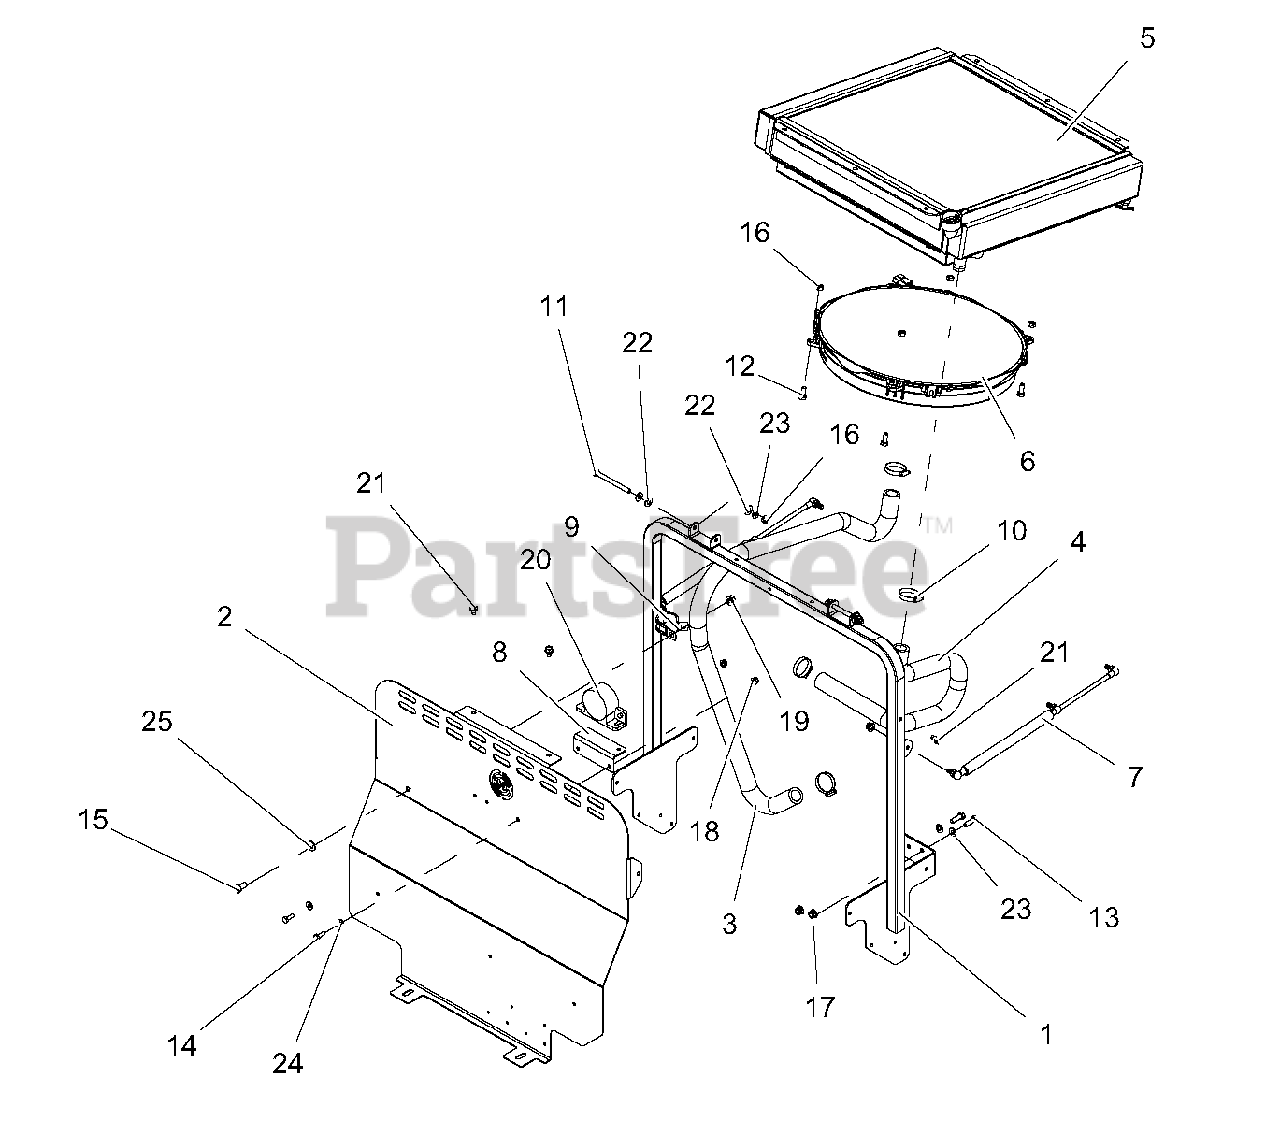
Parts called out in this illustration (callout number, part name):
1	WLDMT, RADIATOR / EXP. TANK MOUNTK-BLAC
2	GUARD, OPERATOR PT400 DIESEL
3	HOSE, FORMED RADIATOR OUTLET
4	HOSE, FORMED RADIATOR INLET
5	RADIATOR, DIESEL PT-400
6	FAN, COOLING 16"
7	Gas Shock
8	BRKT, SIGNAL MOUNT
9	CLAMP, CUSHIONED STEEL5, 1.2
10	CLAMP, HOSE 1.50 X .81 X 1.42
11	BLT-HEX .31-18X3.50 GR5 YWZC
12	BLT-HEX .31-18X.75 GR5 YWZC
13	BLT-HEX .31-18X1.00 GR5 YWZC
14	BLT-HEX .25-20X.75 GR5 YWZC
15	BLT-HEX .38-16X.75 GR5 YWZC
16	@NUT-LK-CTR .31-18 YWZC
17	NUT-LK-NYL-FLG .31-18 YWZC
18	NUT-LK-NYL-FLG .25-20 YWZC
19	@NUT-SPNLK-FLG .375-16 YWZC
20	ALARM, BACKUP
21	SCR-TAP .31-18X.50 HWH TR YWZ
22	WSHR-FL-NYL .375X.75X.060
23	@WSHR-FL-STL.344X.688X.065YWZC
24	@WSHR-FL-STL.281X.62X.065 YWZC
25	@WSHR-FL-STL.406X.812X.065 YWZ
